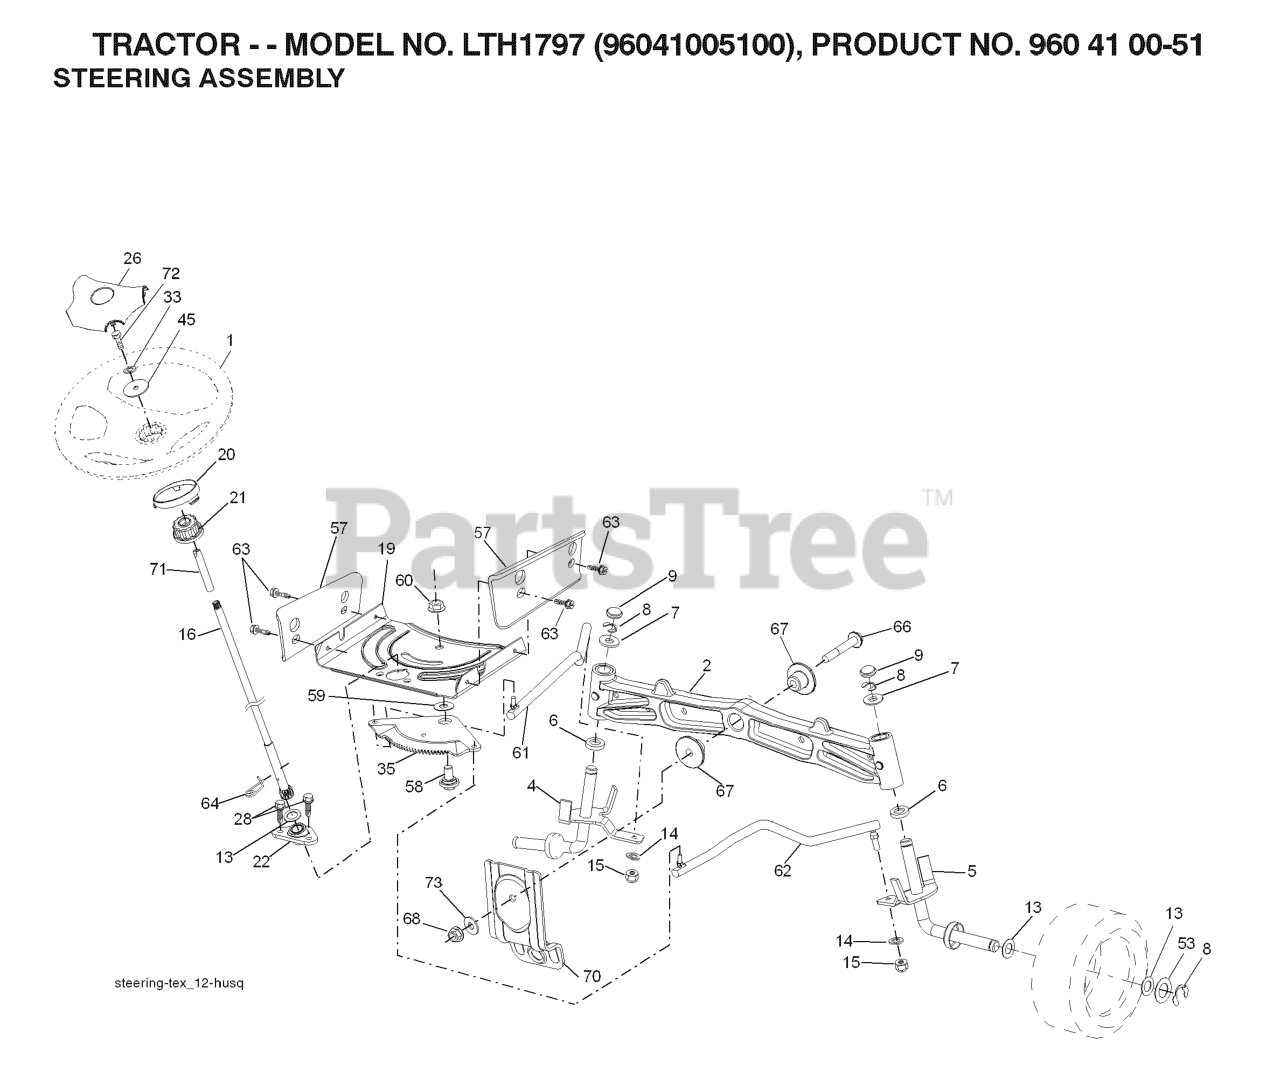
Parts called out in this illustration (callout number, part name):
1	STEERING WHEEL
2	AXLE.CAST.IRON
4	SPINDLE.WELDED.LH.15"TEX
5	SPINDLE.WELDED.RH.15"T
6	THRUST WASHER
9	CAP.SPINDLE.BLACK
14	WASHER, LOCK 3/8
15	NUT CROWNLOCK 3/8-24
16	SHAFT STEERING
19	PLATE.STEER.DDL.NLT/NG
20	BOOT, STEERING
21	ADAPTER, WHEEL STNG..
22	BUSHING.ASM.STEERING.A
26	INSERT.CAP.STRG.WH.GRAY
28	SCREW, 3/8-16X3/4
33	WASHER.LOCK.HVY.HLCL.SPR.5/16
35	GEAR.SECTOR.PLATE.DDL.
45	WASHER.11/32
53	WASHER.HARDENED
57	BRACKET.UPSTOP.TEX
58	BOLT.SHOULDER.SECTOR.P
59	WASHER.THURST.SECTOR.S
60	NUT FLANGE LOCK 5/8-11
61	DRAGLINK.LH.BALLSTUD.D
62	DRAGLINK.RH.BALLSTUD.D
63	SCREW
64	RETAINER.CLIP.SPRING.S
66	BOLT HEX FGHD 7/16-14 X 3 SERR
67	BUSHING.PM.FRONT AXLE
68	NUT.LOCK.FLANGE.7/16
70	BRKT.DECK.SUSPENSION.F
71	SHAFT EXTENSION STEERING
72	BOLT YT
73	WASHER.1.5X.505X.118
